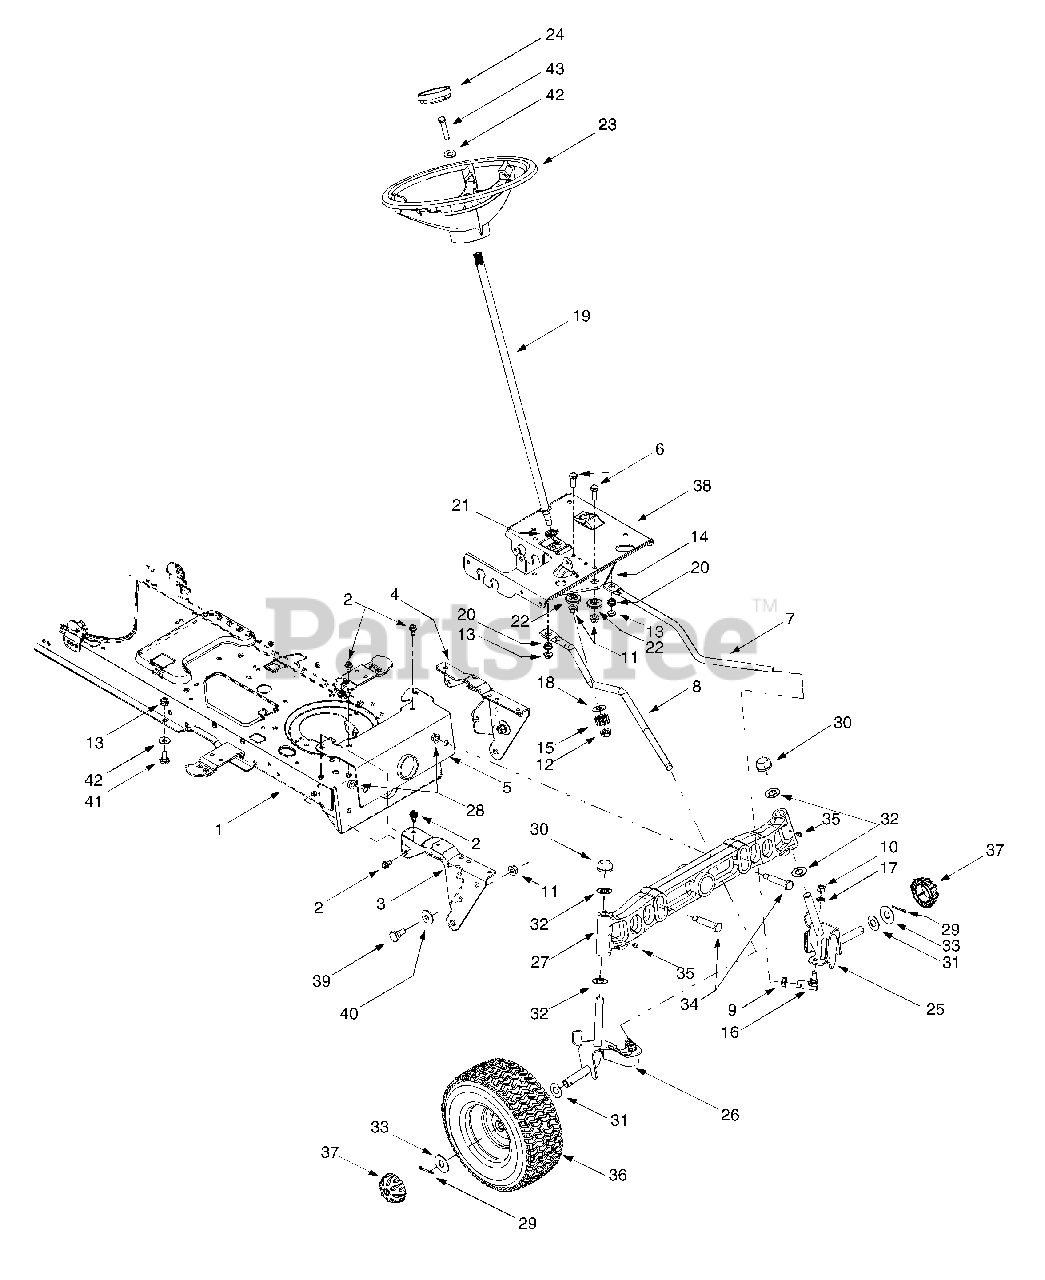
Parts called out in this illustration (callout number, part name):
6	Hex Cap Screw, 3/8-16 x 1 (Grade 5)
7	LH Drag Link
8	RH Drag Link
9	Jam Nut, 7/16-20 (Grade 2)
10	Hex Nut, 3/8-24 (Grade 2)
11	Flange Lock Nut, 3/8-16
12	Flange Lock Nut, 7/16-20
13	Flange Lock Nut, 5/16-18
14	Steering Gear, 11/90 Ratio
15	Steering Pinion Gear
16	Ball Joint, 7/16-20
17	Lock Washer, 3/8
18	Flat Washer, .51 x 1.12 x .06
19	Steering Shaft, .625 OD x 24.4
20	Plastic Bushing, .38 ID
21	Hex Flange Bearing, 5/8
22	Shoulder Spacer, .38 ID
23	Steering Wheel
24	Steering Wheel Cap
25	LH Axle Assembly, .750 Diameter
26	RH Axle Assembly, .750 Diameter
27	Cast Iron Pivot Bar
28	Flange Lock Nut, 3/8-16
29	Cotter Pin
30	Push Cap, .750
31	Flat Washer, .78 x 1.59 x .06
32	Flat Washer, .78 x 1.59 x .06
33	Flat Washer, .78 x 1.59 x .06
34	Shoulder Screw, .5 x 2.2, 3/8-16
35	Lube Fitting, 3/16
36	Wheel Assembly Complete, 16 x 6.5 x 8
36	Rim Only
36	Air Valve
36	Tire Only, Square Shoulder
37	Hub Cap
39	Shoulder Screw, 3/8-16
40	Bell Washer, .39 x 1.13 x .062
41	Shoulder Screw, .435 x .178, 5/16 x .56
42	Bell Washer, .34 x .872
43	Hex Bolt, 5/16-18 X 1
